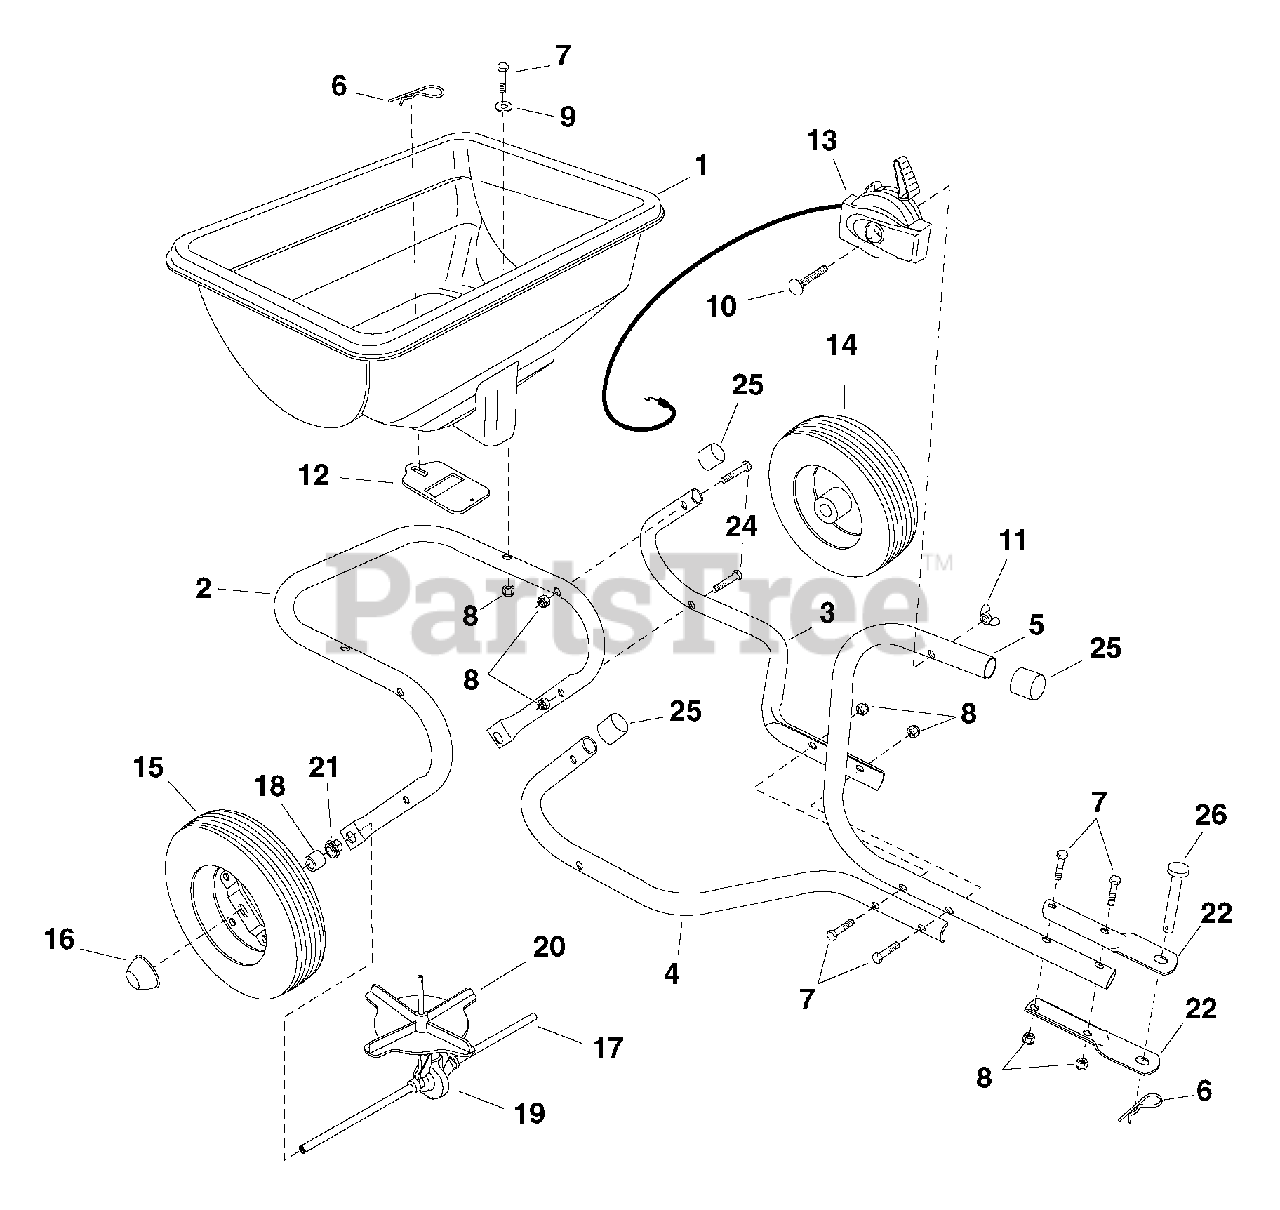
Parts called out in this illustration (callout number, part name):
2	Frame Tube
3	Hitch Tube (LH)
4	Hitch Tube (RH)
5	Hitch Control Tube
6	Hair Cotter Pin
7	Hex Bolt, 1/4-20 x 1-3/4
8	Nylock Nut, 1/4-20
9	Washer, 1/4 Std
10	Carriage Bolt 1/4-20 x 2-1/4
11	Nylon Wing Nut 1/4-20
12	Flow Slide
13	Control Cable
15	Drive Wheel
16	Hub Cap (Push Nut)
19	Gearbox
20	Impeller
21	Hex Flange Bearing
22	Hitch Bracket
23	Hitch Pin
24	Hex Bolt, 1/4-20 x 2-1/4
25	Vinyl Cap
